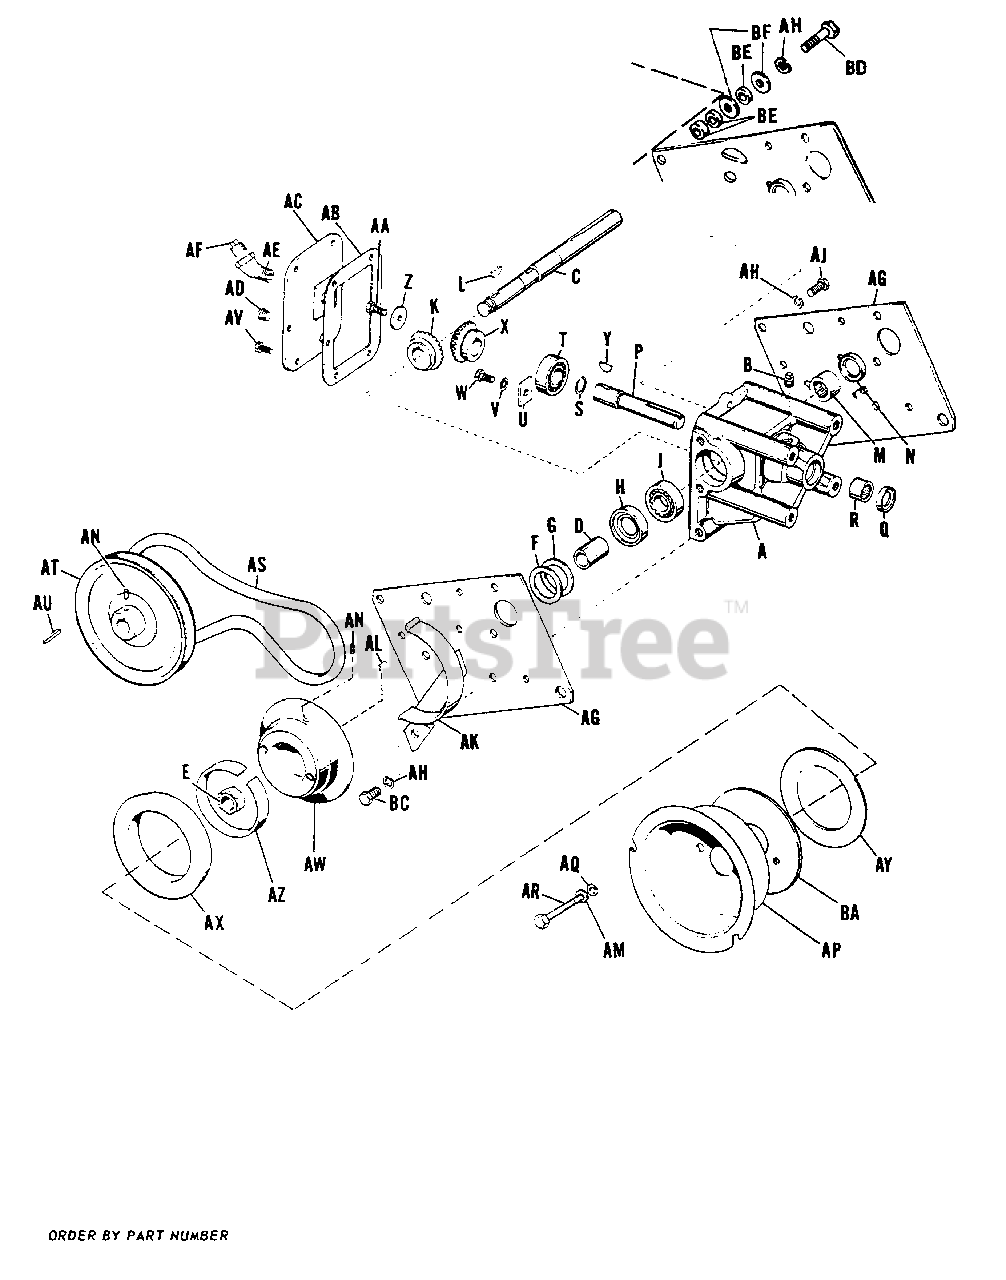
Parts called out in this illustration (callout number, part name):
A	Housing, Bevel Gear, Complete w/2 needle brgs.
B	Plug, Pipe
C	Drive Shaft (164114 on 568 & 569)
D	Spacer, Pulley
E	Nut, Hex., Jam
F	Shim (as required)
H	Seal, Oil (157669 on 568 & 569)
J	Bearing, Ball
K	Gear, Bevel, Driven
L	Key, Woodruff
M	Bearing, Needle
P	Shaft, Driver
R	Bearing, Needle
S	Ring, Retaining
T	Bearing, Ball
U	Plate, Bearing Clamp
V	Washer, Lock, 5/16"
W	Screw, Cap, Hex., 5/16"-18 N.C. x 5/8" lg.
X	Gear, Bevel, Driver
Y	Key, Woodruff
AA	Screw, Cap, Hex., 5/16"-18 N.C. x 3/4" lg.
AC	Cover Assy., Housing (164249 on 496, 498, 568 & 569)
AD	Plug, Pipe
AE	Elbow, Street (72850 on 496, 497, 568 & 569)
AF	Plug, Pipe
AG	Plate, Side (164056 on 496 & 497 See Note 1)
AH	Washer, Lock, 7/16"
AJ	Hex. Capscrew, 7/16"-14 N.C. x 1" lg. (705064 on 568 & 569)
AK	Guard Assembly, Belt
AL	Key, Woodruff
AM	Plain Washer, 5/16"
AN	Set Screw, Cup Pt. Sock. Hd., 5/16"-18 N.C.x 5/16" lg.
AP	Pulley, Rope Starter
AQ	Washer, Lock, 5/16"
AR	Hex. Capscrew, 5/16"-18 N.C. x 7/8" lg.
AS	Belt, V-Drive
AT	Pulley, Drive
AU	Key
AV	Hex. Capscrew, 1/4"-20 x 5/8" lg.
AW	Pulley Half
AX	Pulley Half
AY	Thrust Washer
AZ	Bearing
BA	Thrust Washer
BC	Screw, Cap Hex., 7/16"-14 x 1-1/4"
BD	Hex Capscrew, 7/16"-14 x 2" lg.
BE	Spacer
BF	Washer, 7/16"
BH	Lock Washer, 7/16"
